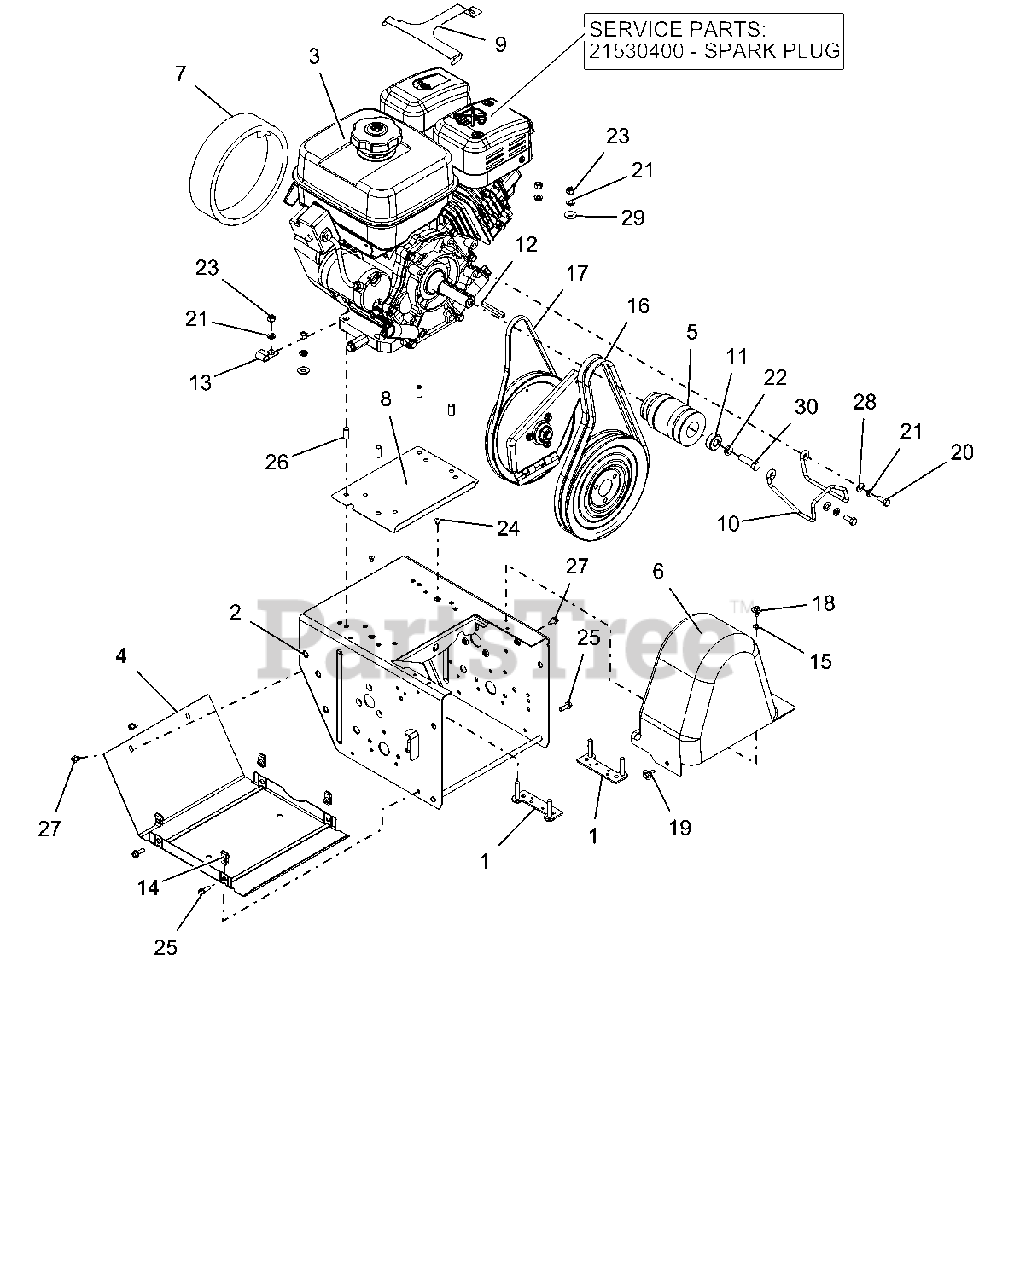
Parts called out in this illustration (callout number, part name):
1	STRAP, ENGINE BOLT-LARGE BRIGG
2	FRAME, MAIN - PRO SNOW
3	PLUG, SPARK - TEC. SNO-THRO
3	ENGINE,SUBARU EX27 AS 120V
4	COVER, BOTTOM
5	SHEAVE, SUBARU EX27
6	COVER, BELT-TALL PRO
7	FOAM COVER, RECOIL-SUBARU
8	BAFFLE, WATER-PRO SERIES
9	GUARD, SNOW-SUBARU
10	FINGER, BELT
11	BSHG-SPACER .47X1.25X.50
12	KEY .25X.25X2.25
14	NUT-RTNR .25-20X.56
15	NUT-PUSH .25X.50 O.D.
16	V-BELT, HA-RAW EDGE (SET)
17	V-BELT, 3L-RAW EDGE
18	SCR-TAP .25-20X.50 LGHWH TR YZ
19	SCR-TAP .25-20X.5 CAPTIVE
20	BLT-HEX .31-24X.75 YWZC GR5
21	WSHR-LK .312X.097 HVY YWZC
22	WSHR-LK .44X.109 REG YWZC
23	NUT-HEX .31-18 YWZC
24	RVT-POP .187 YZ
25	BLT-HEX .25-20X.75 HWH YZ GR5
26	BSHG-SLV .325X.400X.795
27	SCR-TAP .25-20X.50 HWH TR YWZ
28	WSHR-FL-STL.344X.688X.065YWZC
29	WSHR-FL-STL.38X.875X.083 YWZC
30	BLT-HEX .44-20X1.50 G5 YZ EP80
